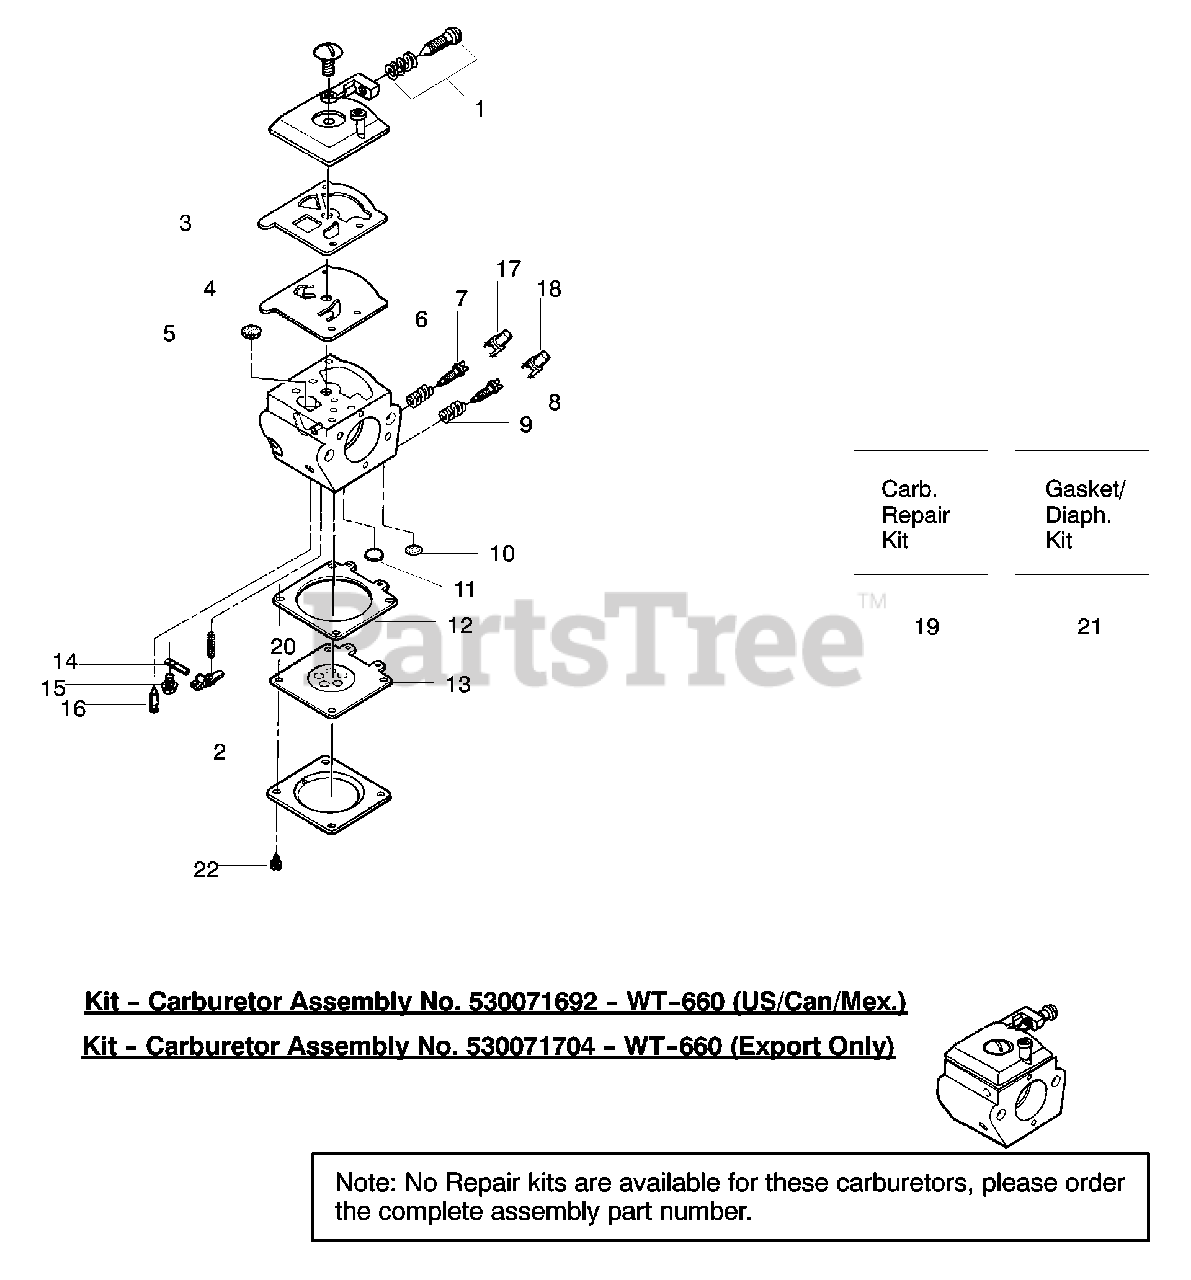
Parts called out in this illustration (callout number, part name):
1	Idle Adv. Screw Kit
2	Metering Lever
3	Fuel Pump Gasket
4	Fuel Pump Diaphragm
5	Fuel Inlet Screen
6	Needle Spring (Low Speed)
7	Low Speed Needle
8	High Speed Needle
9	Needle Spring (High Speed)
10	Welch Plug (5/16)
12	Metering Diaphragm Gasket
13	Metering Diaphragm
14	Metering Lever Pin
15	Metering Lever Pin Screw
16	Inlet Needle Valve
17	Limiter Cap High
18	Limiter Cap Low
19	Carburetor Repair Kit
20	Metering Lever Spring
21	Gasket/Diaphragm Kit
22	Metering Cover Screw Ass'y
530071692	Kit - Carburetor Assembly WT-660 (US/Can/Mex.)
530071704	Kit - Carburetor Assembly WT-660 (Export Only)
